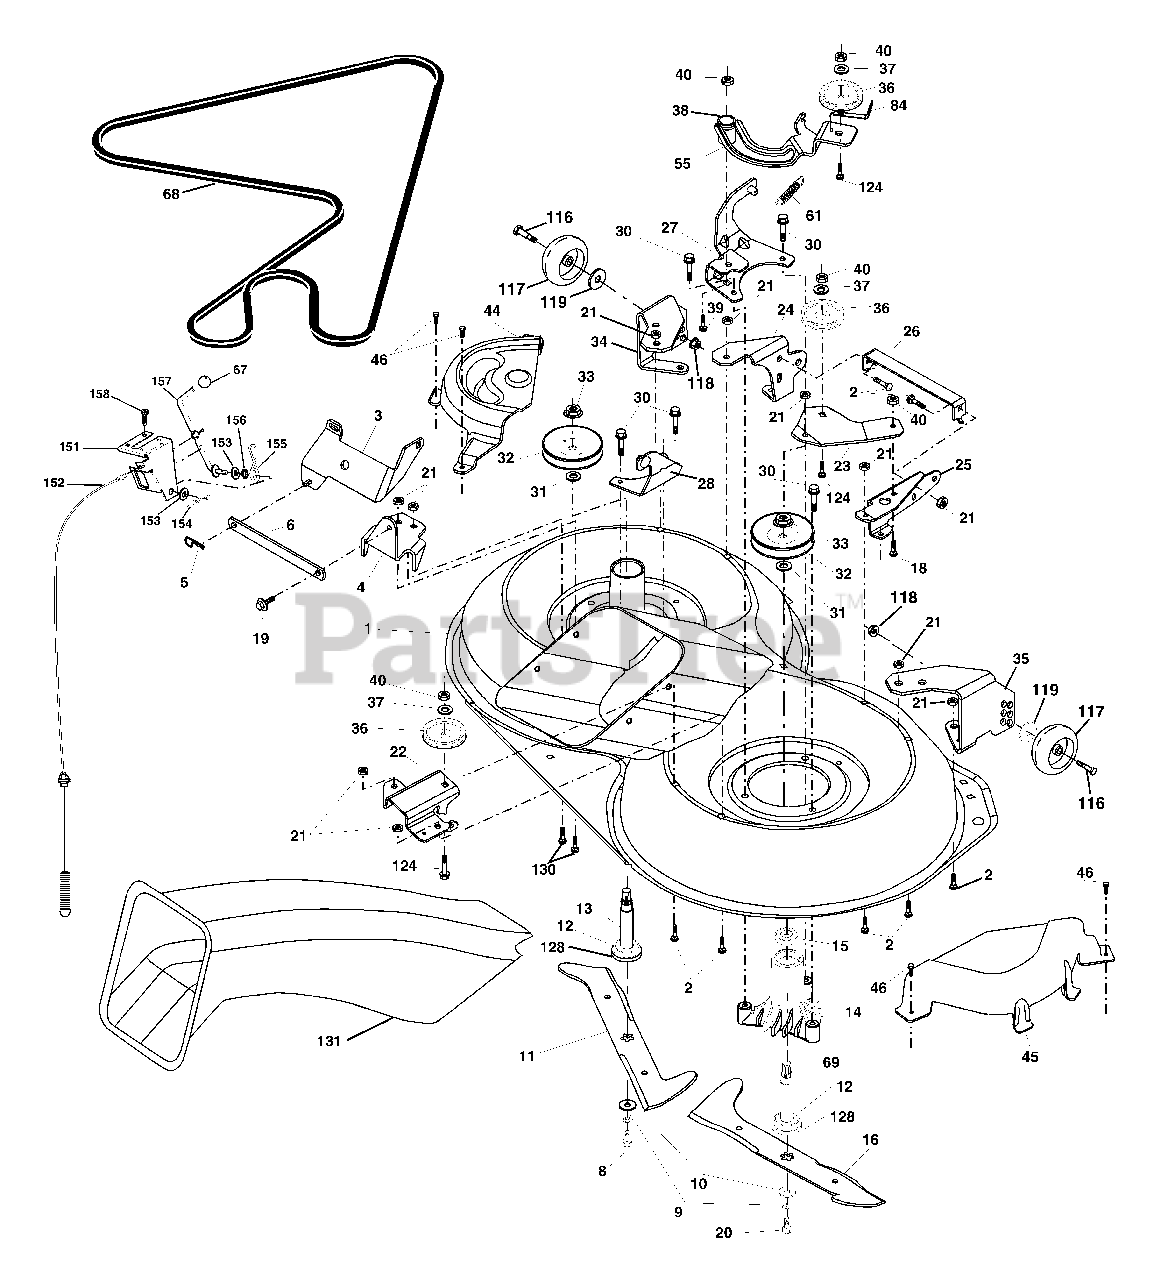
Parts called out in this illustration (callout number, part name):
1	Housing Asm. Mower 107 CRD
2	Bolt Rdhd Sqnk 5/16-18 Unc x 3/4
3	Bracket Asm. S-Bar Chass 92 CRD
4	Bracket Bar Sway Deck 107 CRD
5	Retainer Spring
6	Bar Sway 92 CRD
8	Bolt 3/8-24 x 1.25 Gr8 Patched
9	Washer Lock Hvy 3/8 Unplated
10	Washer Hard Blade Mower vented
11	Blade 3-1 Lh 107 CRD
12	Bearing Ball #6204 (Mandrel)
13	Shaft Asm. W/Lower Bearing
14	Housing Mandrel Vented (Machd)
15	Bearing Ball Mandrel
16	Blade 3-1 Rh 107 CRD
18	Bolt Rdhd Sqnk 3/8-16 x 1 Gr5
19	Bolt Shoulder 5/16-18 Thd Form
20	Bolt 3/8-24 x 1.25 Gr8 Ptch Lhthd
21	Nut Crown Lock 5/16-18
22	Bracket Idler Sprt RR 107 CRD
23	Bracket Idler Sprt RF 107 CRD
24	Bracket Suspension LF 107 CRD
25	Bracket Suspension RF 107 CRD
26	Brace Support Susp Frt CRD
27	Bracket Asm. Susp RR 107 CRD
28	Bracket Asm. Susp LR 107 CRD
30	Screw Thd Rolling Washer Head
31	Washer Spacer Mower Vented
32	Mandrel Pulleys
33	Nut Flg Top Lock Cntr B 9/16
34	Bracket Gauge Wheel Lf 107 CRD
35	Bracket Gauge Wheel Rf 107 CRD
36	Pulley Idler V-Groove Dim 4.25
37	Washer 11/32 x 13/16 x 16 Ga
38	Spacer Hub Arm Idler 107 CRD
39	Bolt Rdhd 3/8-16 Unc x 2-3/4 Gr. 5
40	Nut Crownlock 3/8-16 Unc
44	Cover Mandrel Lh 107 CRD
45	Cover Mandrel Rh 107 CRD
46	Screw Thd Roll 1/4-20 x 5/8
55	Arm Idler 107 CRD
61	Spring Tension Belt
67	Knob Rd 3/8-16 Plstc Thds Blk
68	Hex-Belt 107 Mower
69	Shaft Asm W/Lwr Brg Rh Thd CRD
84	Keeper Belt Idler
116	Bolt Shoulder
117	Wheel Gage Donut Wide
118	Nut Centerlock 3/8-16 Unc
119	Washer 3/8 x 7/8 x 14 Ga.
124	Bolt Carr Sh 3/8-16 x 1-1/2 Gr5
128	Washer Felt
130	Bolt Rdhdsqnk 5/16-18 Unc x 3/4
131	Chute Bagger CRD 92cm
151	Bracket Clutch Cable
152	Cable Clutch CRD Service
153	Washer Flat 3/8" Type B
154	Spring Retainer
155	Spring Retention Lvr Clutch Cable
156	Spacer Clutch Cable
157	Rod Clutch Cable 3/8"
158	Screw Hex Thd Cut 1/4-20 x 5/8
